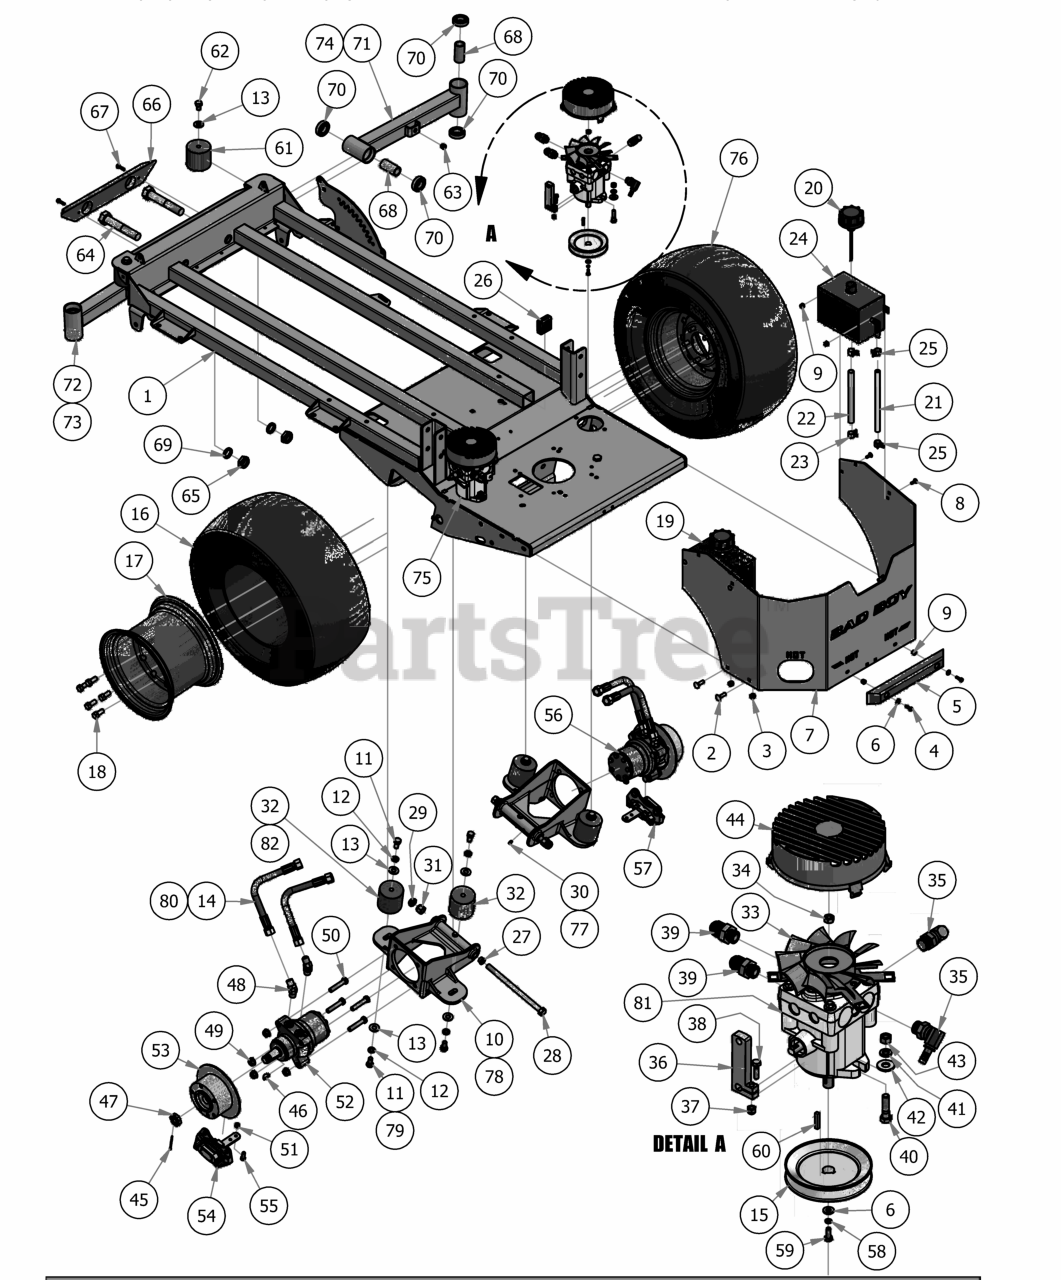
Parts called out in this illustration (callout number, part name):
1	2017 XP Frame
2	3/8" x 1 1/4" Carriage Bolt
3	3/8 Nylock Nut
4	1/4-20 x 1-1/4 GR 5 Hex Bolt
5	14" Rubber Bumper
6	1/4" Flat Washer
7	Outlaw Rear Plate
8	1/4" x 3/4" Carriage Bolt
9	1/4-20 Nylon Insert flange Nut
10	60 Suspension kit Wheel Motor
11	1/2" x 1" Hex Bolt
12	1/2" Lock Washer
13	1/2" Washer (Grade 8)
14	18" hose Assembly W/forged 45 Degr
15	5" Pump Pulley
16	2018 24x12-12 Reaper Turf Tire
17	12x12" Black Wheel For 2015 Outlaw
18	1/2-20 x 1-1/2 Lug Bolts Zinc
19	Outlaw Hydraulic Tank Left
20	Hydraulic Tank Cap W/Dipstick
21	3/8" Clear Hose
22	1/2 Clear Braded Hose Priced/Foot
23	1/2 Hose Clamp
24	Outlaw Hydraulic Tank Right
25	3/8" Hose Clamp
26	2X2 Frame Plug
27	Flange Bushing for Deck Arm - Upper
28	5/8''x10'' Hex Bolt (Grade8)
29	5/8" Nylock (1/2 Jam)
30	1/4" Drive in Grease Fitting (72" Suspension Kit Wheel Moter)
31	5/8 Std NC Nylock Nut
32	Vibration Mount-Green Dot
33	Hydraulic Fan
35	3/8" X 9/16"-18 ORB Male Fitting (S,A-2 P-4)
37	1/4" Nylock Nut
38	1/4-20 x 1 GR 5 hex bolt zinc
39	Hydraulic Pump Fitting 6400-10
40	3/8" x 1 1/2" Hex Bolt
41	3/8" Lock Washer
42	3/8" Flat Washer
43	3/8" Hex Nut
44	Fan Guard 6" Fits wheel Motor Pumps
45	1/8x2-1/4 cotter pin Zinc
46	Woodruff Key
47	1" Castle Nut for Wheel Motor
48	45 Degree Fitting 31704-10-10
49	1/2" Flange Nut
50	1/2" x 2 1/2" Hex Bolt
51	5/16-18 Nylock Insert Locknut
52	15cc Parker Wheel Motor- Left
53	Brake Disk
54	XP/AOS Left Brake Caliper
55	3/8" x 1" Hex Bolt
56	15cc Parker Wheel Motor- Right
57	XP/AOS Right Brake Caliper
58	1/4" Lock Washer
59	M6-1.0 X 16MM Hex Bolt
60	5MM X 1 Square Key Stock
61	Vibration Mount- Red Dot
62	1/2" x 3/4" Hex Bolt
63	5/8 Round Insert
64	1-14 x 5.5 Hex Bolt Grade 8 Zinc Yellow
65	1" Fine Thread Nut
66	2017 XP Bumper
67	1/4 x 1 Hex Head Tek screw
68	2016 Front Bearing Spacer
69	1" x .25" Spacer
70	Caster Bearing 2016 - 1641 Bearing
71	2017 XP Suspension Arm - Right
72	2017 XP Arm Assembly - Left
73	2017 XP Suspension Arm -Left
74	2017 XP Arm Assembly - Right
75	Left Pump 12cc
76	2018 24x12-12 Reaper Turf Tire and Black Wheel Assembly
77	3/8" Threaded Grease Fitting (60" Suspension Kit Wheel Moter)
78	72" Suspension Kit Wheel Motor
79	1/2-13 x 1 1/4 Hex Bolt (Only on 60" Suspension Kit Wheel Motor)
80	18" Hydraulic Hose Only
81	Right Pump 12cc
82	Vibration Mount-Blue Dot
